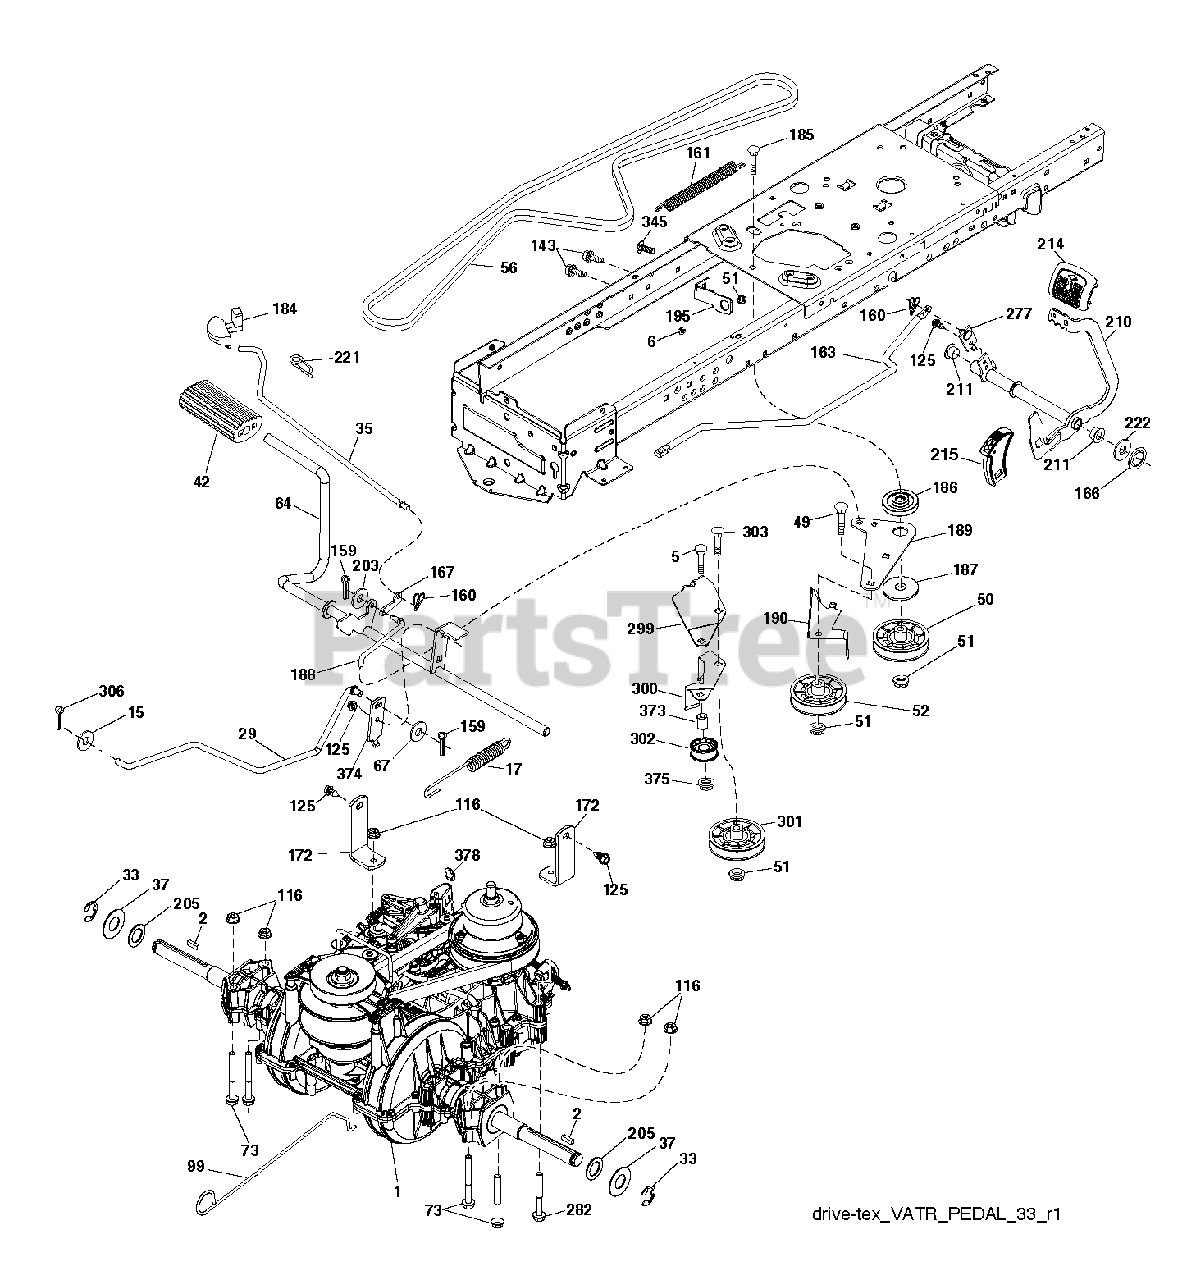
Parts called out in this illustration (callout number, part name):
2	SQUARE KEY
6	GROMMET T
15	WASHER
17	Brake Variator Spring
29	RB ROD.BRAKE.VARIATOR.SD2
33	E-RING LT
35	ROD.CNTRL.PARK.PREDATOR.LT.TEX
37	WASHER.HARDENED
49	BOLT
50	IDLER.FLAT.910.OFFSET
51	NUT LOCK FLG 3/8-16 UNC
52	IDLER.V-GROOVE.910.OFFSET
56	BELT.DRIVE.MOWER.TEX.42"
64	Variator Shaft, Pedal Cross
67	Washer, Nylon 1332 X 1316
73	BOLT HEX 5/16-18 GR 5
99	ROD.BYPASS.VARIATOR.GEN2
116	NUT LOCK HEX FLANGE 5/16-18
125	SCREW
143	SCR 5/16-18 X 1/2 SELFTAP ZN
159	COTTER PIN
160	RETAINER CLIP
161	SPRING, RETURN LT
166	NUT.PUSH.625
167	LATCH.BRAKE.SPRING
172	STRAP.TORQUE.VARIATOR
184	Parking Brake Handle
186	SPACER.RETAINER
187	WASHER 12/32X2X10GA
188	Ground Drive Clutch Link, Long
189	BELLCRANK.GROUND.DRIVE.TEX.
190	KEEPER.BELLCRANK.DRIVE
195	BRACKET.BRAKE.BRAKE.VAR.SD
203	WASHER
210	PEDAL.ASM.ROCKET.VARIATOR.LT
211	BEARING.NYLON
214	PEDAL.FORWARD.PAD.TEX
215	CAP.PEDAL.REVERSE.VARIATOR
221	RETAINER.SPRING.CLIP.H
222	WASHER 21/32 X 1-1/4 X 10 GA.
277	SUBASM.LINK.ROCKER.PEDAL
282	BOLT HEX FLGHD 5/16-18X3 GR. 5
299	BRACKET.MOUNT.IDLERS
300	KEEPER.IDLERS.REAR.VARIATOR
301	PULLEY.IDLER.V-GROOVE
302	PULLEY.IDLER.FLAT.2"
303	BOLT CARRIAGE
306	PIN COTTER
374	ARM.CONTROL.BRAKE
375	LOCKNUT
378	NUT.PUSH.8MM
